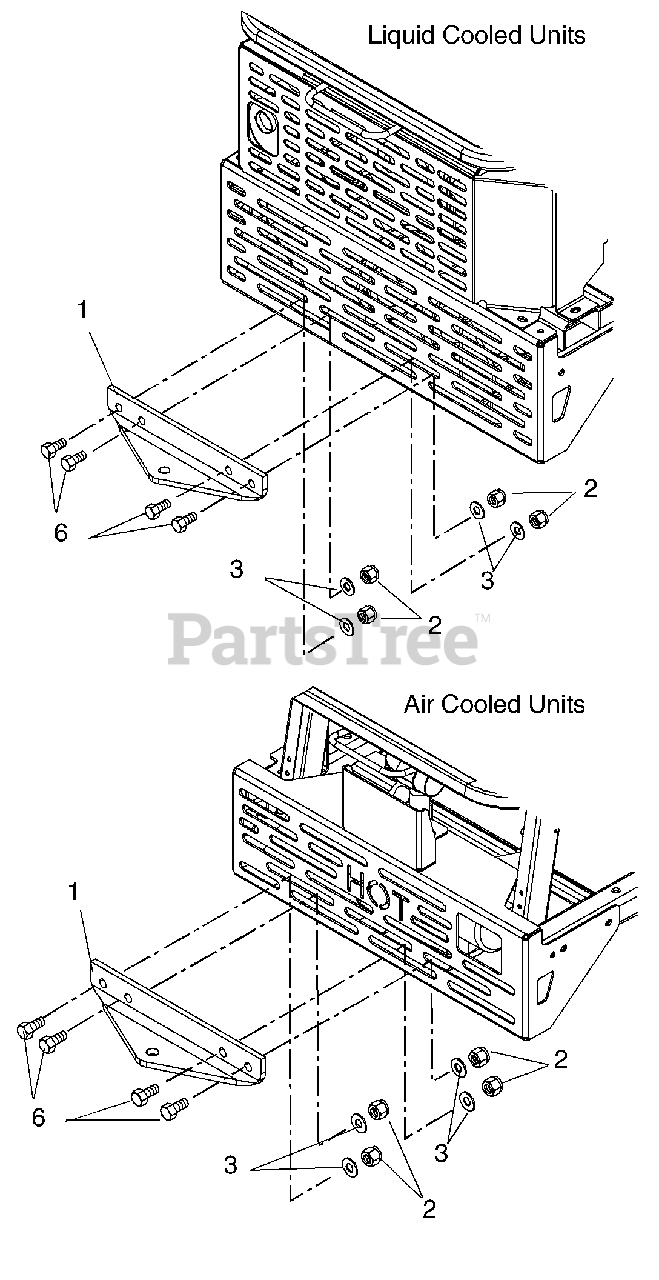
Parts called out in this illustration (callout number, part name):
1	Hitch Plate
2	1/2" Nylon Locknut
3	Flat Washer
6	1/2" x 1-1/4" Hex Bolt
